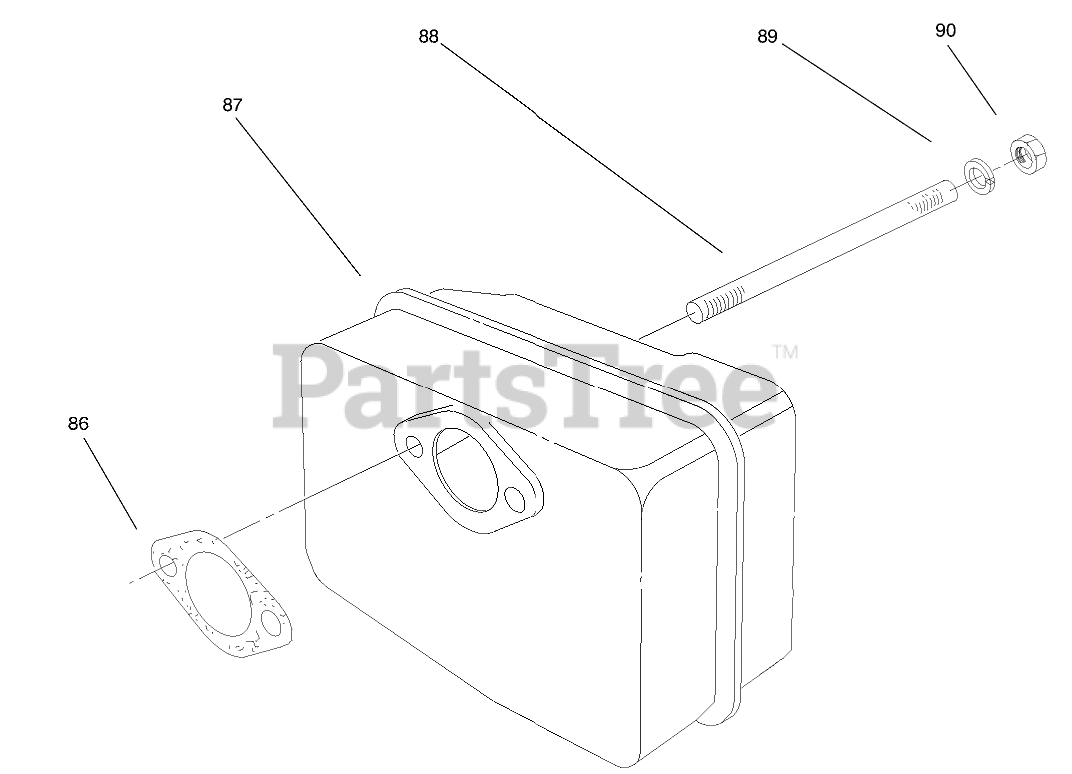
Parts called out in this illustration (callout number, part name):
78	SCREW
79	GASKET
86	GASKET
87	MUFFLER
89	WASHER-LOCK
